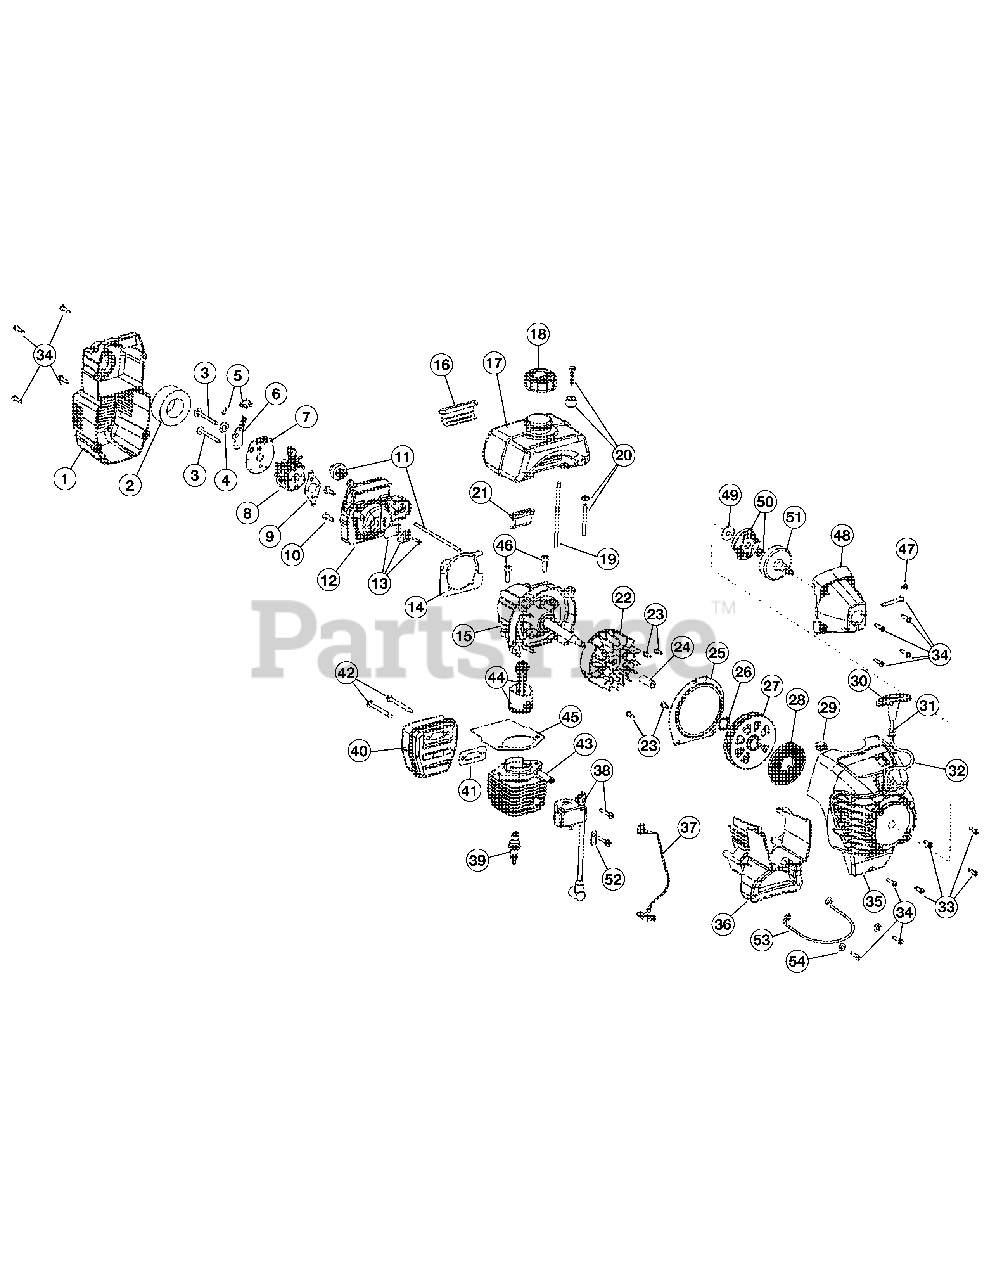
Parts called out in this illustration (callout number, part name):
1	Air Cleaner Cover Assembly
2	Air Cleaner Filter
3	Carburetor Mounting Screws
4	Wavey Washer
5	Choke Knob & Screw
6	Choke Lever Assembly (includes 5)
7	Choke Lever & Plate (includes 6)
8	Carburetor Assembly (includes 9 & 20)
9	Carburetor Gasket
10	Carb Mount Screw
11	Primer and Hose Assembly
12	Carburetor Mount Assembly (includes 10, 13 & 14)
13	Reed Assembly
14	Carburetor Mount Gasket
15	Crankcase Service Assembly (includes 10)
16	Rear Mounting Pad
17	Fuel Tank Assembly (includes 18 & 20)
18	Fuel Cap Assembly
19	Fuel Return Line
20	Fuel Line Assembly
21	Front Mounting Pad
22	Flywheel Assembly
23	Plate Screw
25	Pressure Plate (includes 23)
26	Palnut
27	Recoil Pulley Assembly (includes 26 & 32)
28	Recoil Spring
30	Pull Handle
31	Rope Guide
33	Housing Screw
34	Cover Screw
35	Starter Housing Assembly (includes 23, 25-34)
36	Shroud Extension and Stand
37	Wire Lead
38	Module Assembly
39	Spark Plug
40	Muffler Assembly (includes 41, 42, and spark arrestor)
41	Exhaust Gasket
42	Muffler Mounting Bolt Assembly
43	Cylinder Assembly (includes 45 & 46)
44	Piston & Rod Assembly
45	Cylinder Gasket
46	Cylinder Bolt
47	Anti-Rotation Screw
48	Clutch Cover Assembly (includes 34 & 47)
49	Washer
50	Clutch Assembly
51	Clutch Drum
53	Wire Footstand (includes 34 & 54)
